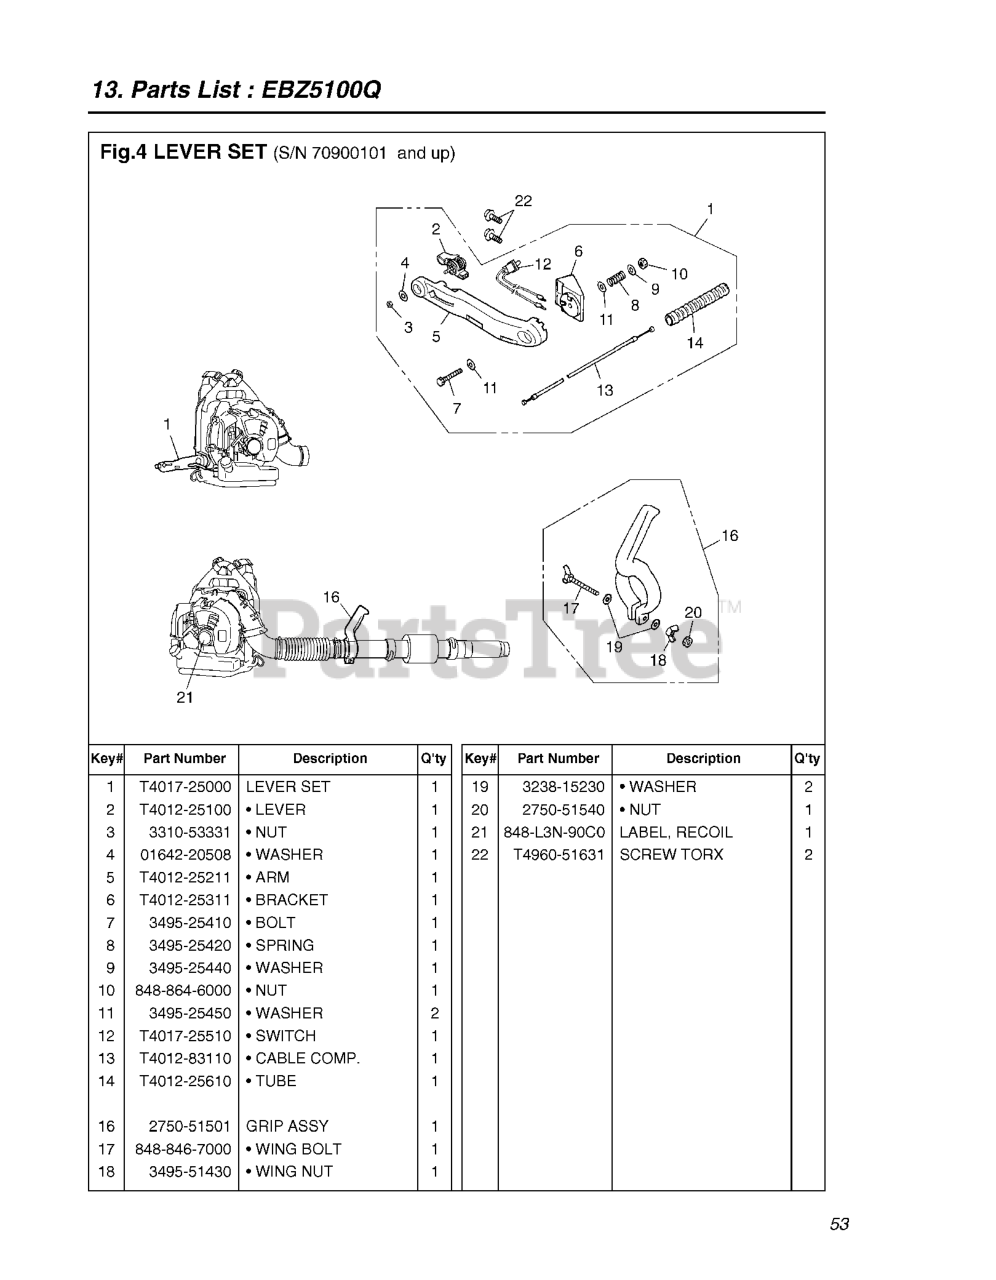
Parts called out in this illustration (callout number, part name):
1	LEVER SET
4	WASHER
5	ARM
9	WASHER Z349525440
10	NUT 8488646000
13	RP_CABLE COMP
16	GRIP ASSY
17	WING BOLT
18	WING NUT
19	WASHER
